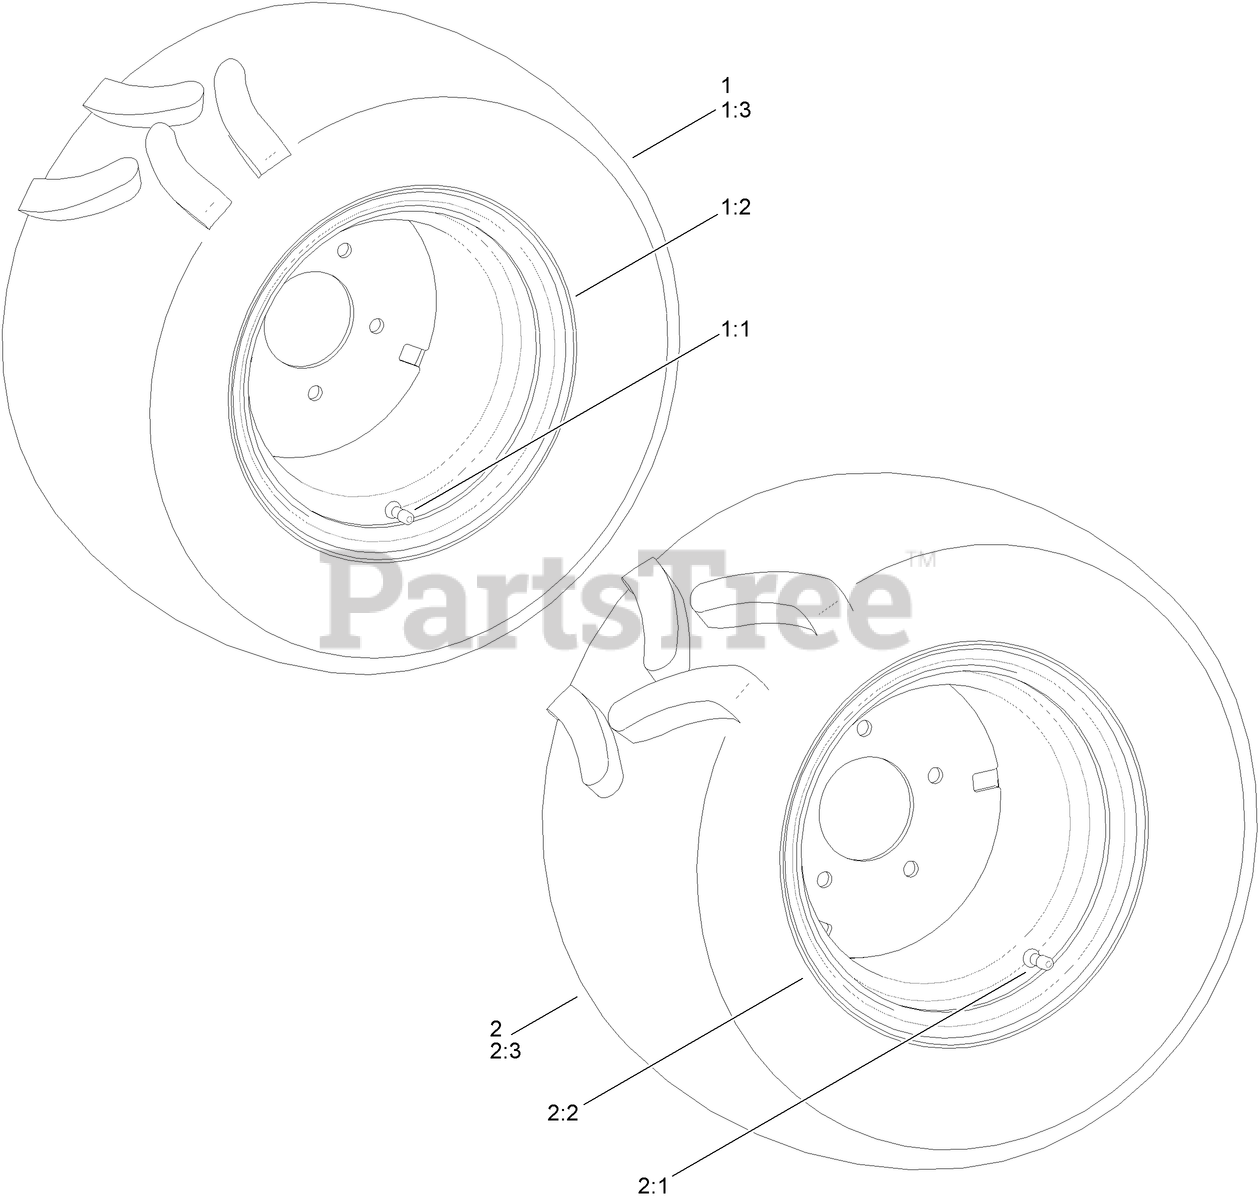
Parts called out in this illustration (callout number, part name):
1	RH WHEEL AND TIRE ASM
1:1	STEM-VALVE
2	LH WHEEL AND TIRE ASM
2:1	STEM-VALVE
